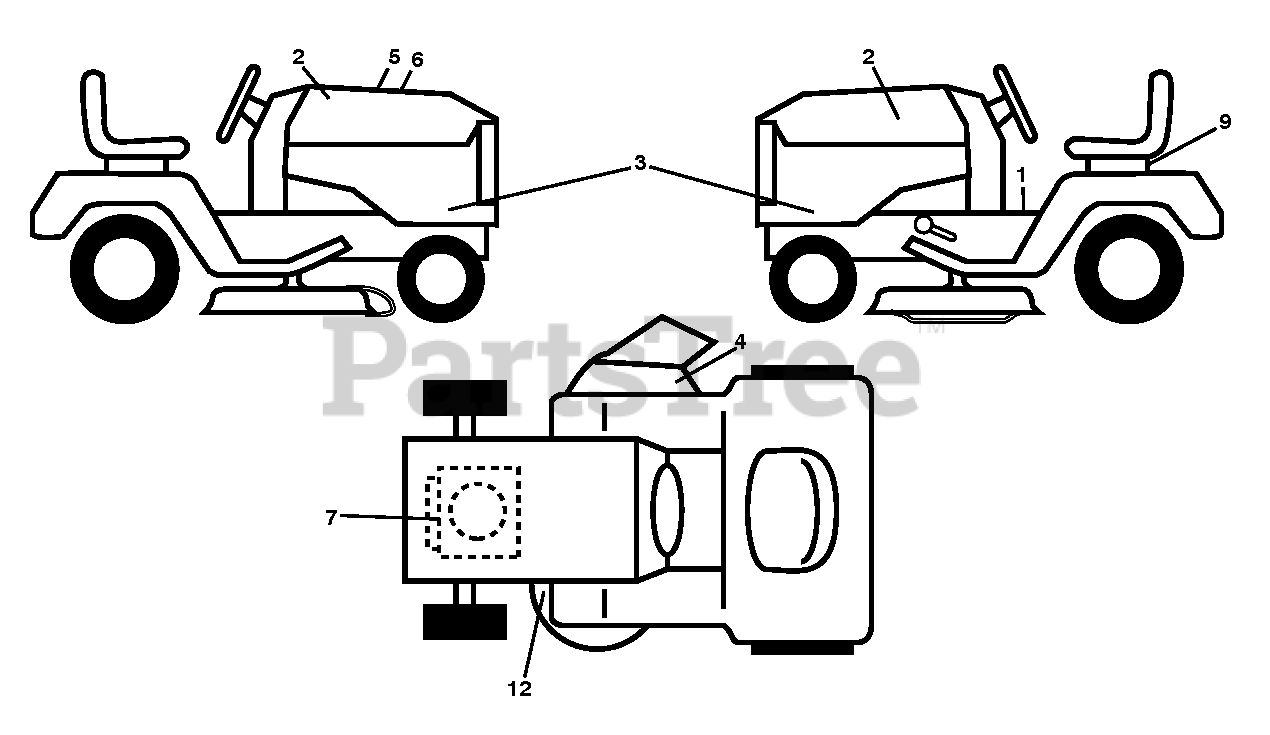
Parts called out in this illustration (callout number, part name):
1	DECAL.FENDER.WARNING.ENGLISH
2	RP.DECAL.BADGE.170MM.TEXTLOGO
3	DECAL.SIDE.PANEL.YTH22V46.2013
4	DECAL.MOWER.WARN.KEEP.HAND.AWY
5	DECAL.WARNING.CUST.RESP.E85.
7	DECAL.ENG.BS.22HP.INTK
9	DECAL BTRY SYMBOLS
12	DECAL.V-BELT.SCH.42/46"MEC/ELE
